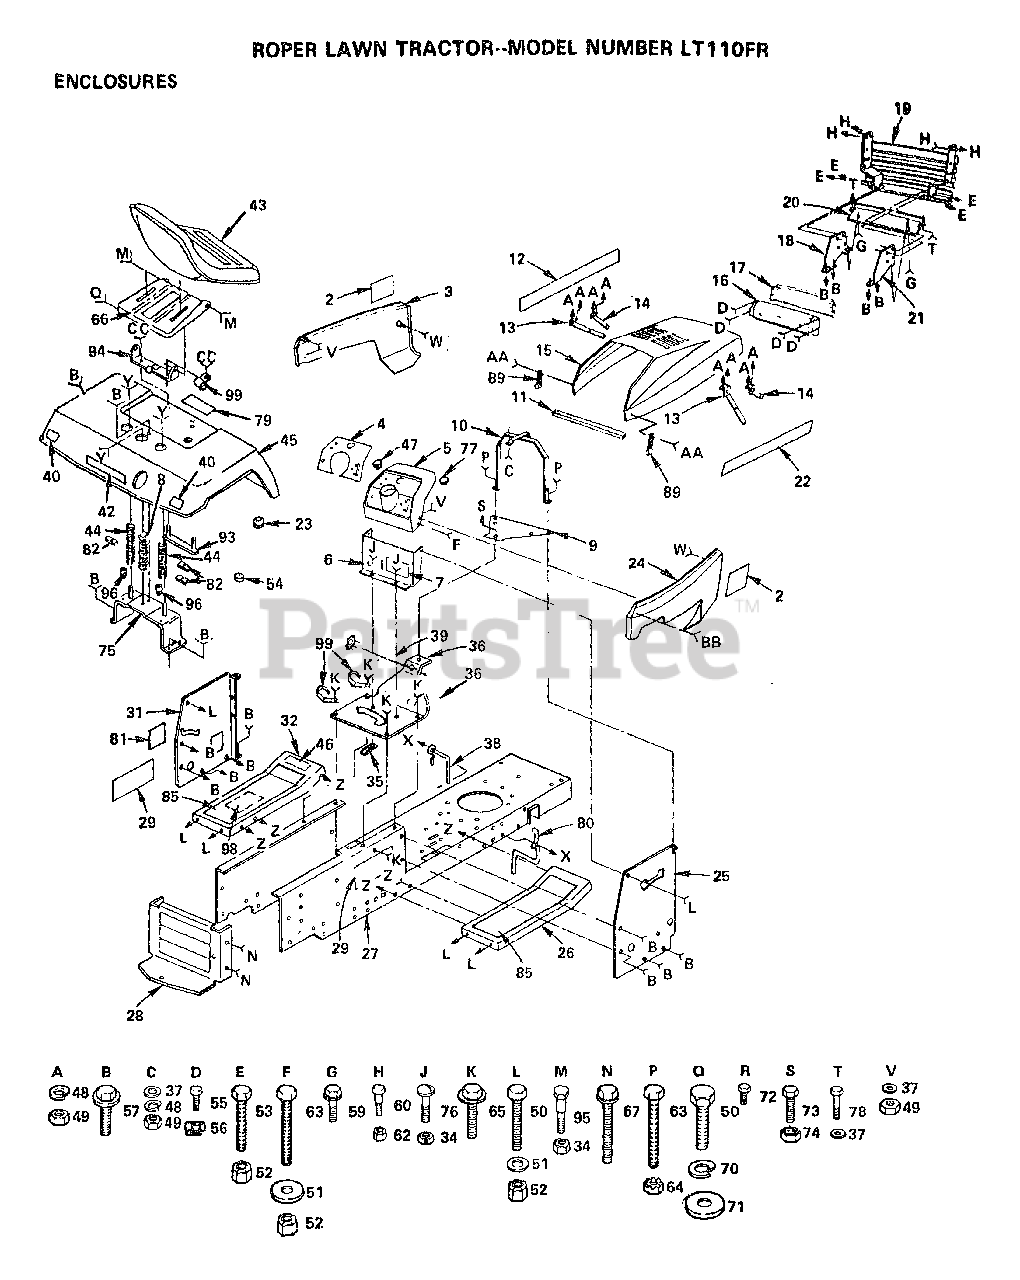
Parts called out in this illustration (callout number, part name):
1	LOCKWASHER
6	DASH ASSY LT
8	SPRING T
10	SUPPORT ASSY LT
11	FOAM-STRIP LT
17	LENS LT
18	SUPPORT-GRILL LT
23	GROMMET T
25	PANEL DASH RH YT
31	PANEL DASH HYT
37	WASHER PM
40	REFLECTOR-TAIL YT
47	PLUG-DASH T
51	WASHER
53	BOLT
56	"""J"" FASTENER LT"
57	SCREW
59	SCREW
60	BOLT T
64	NUT
65	SCREW LT
66	SEAT PAN T
67	SCREW
69	BOLT
70	LOCKWASHER
71	WASHER T
73	BOLT
76	SCREW
77	PLUG BUTTON T
78	SCREW HEX CRT
82	"CLAMP, SPRING LT"
94	BRKT.ASM.SEAT.P
96	NUT-PUSH YT
99	CLIP T
